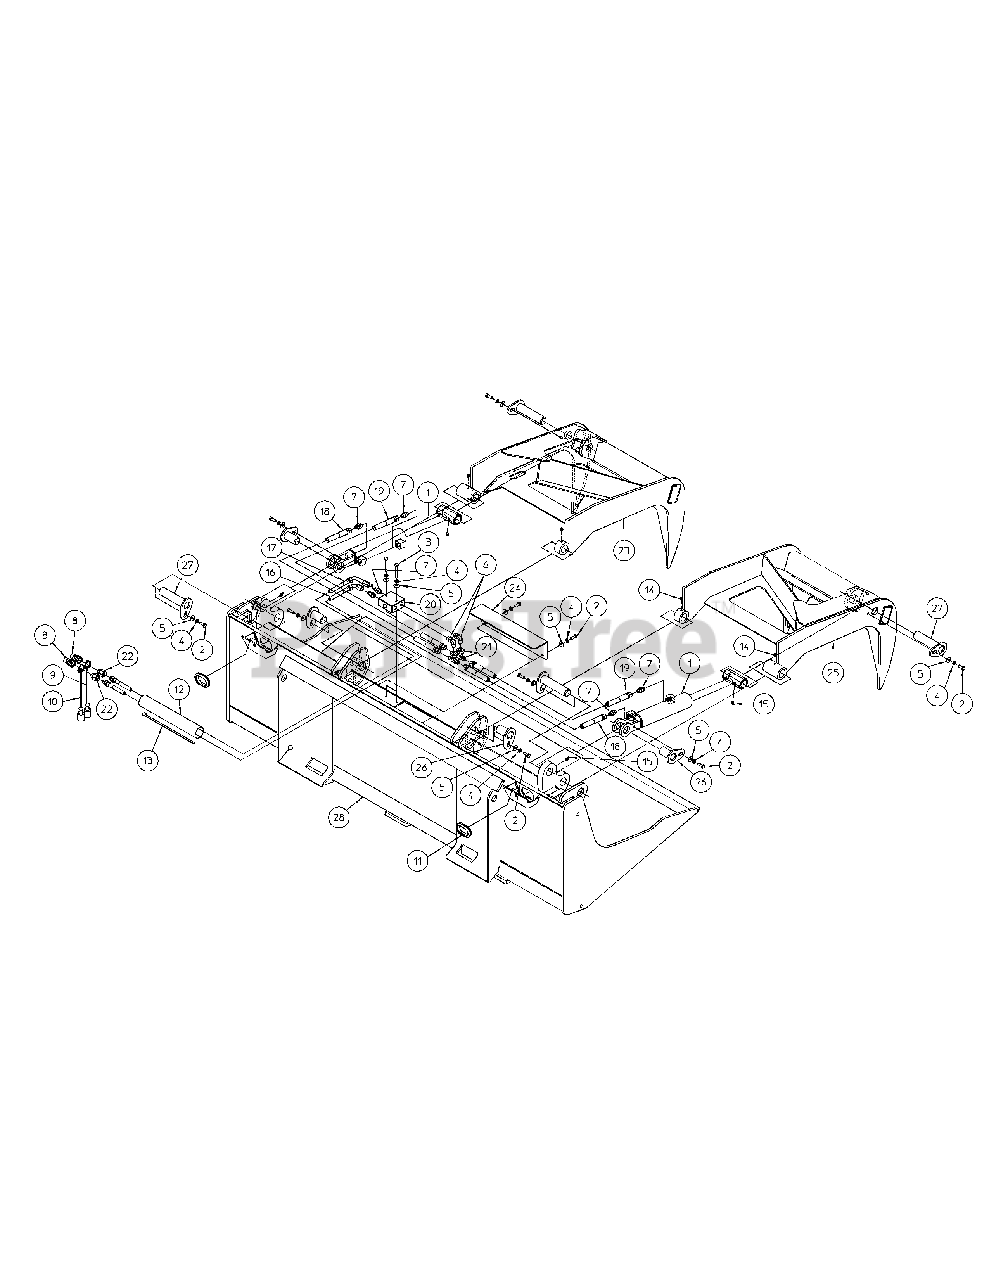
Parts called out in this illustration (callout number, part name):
1	Hydraulic Cylinder Assembly
2	Bolt, Hex NC 5/16" x 7/8" Long
3	Bolt, Hex SAE 2 NC 5/16" x 2-1/4"
4	Lock Washer, MW 5/16"
5	Flat Washer, 5/16"
6	Straight Thread Elbow 90 Degree
7	Straight Thread Connector
8	Coupler Nose
9	Dust Cap, Red
10	Dust Cap, Yellow
12	Hose Sleeve
13	Plastic Tie
14	Grease Fitting, 1/4
15	Grease Fitting, 45 degree
16	Hydraulic Hose, 1/4" x 78"
17	Hydraulic Hose, 1/4" x 78"
18	Hydraulic Hose, 3/8" ID x 40"
19	Hydraulic Hose, 3/8" ID x 49"
20	Check Valve
21	Swivel Nut Branch Tee
22	Fitting, Hydraulic Adapter
23	LH Fork Weldment
24	Valve Cover
25	RH Fork Weldment
26	Short Pivot Pin Weldment
27	Long Pivot Pin Weldment
28	Grapple Bucket Weldment with Decal
